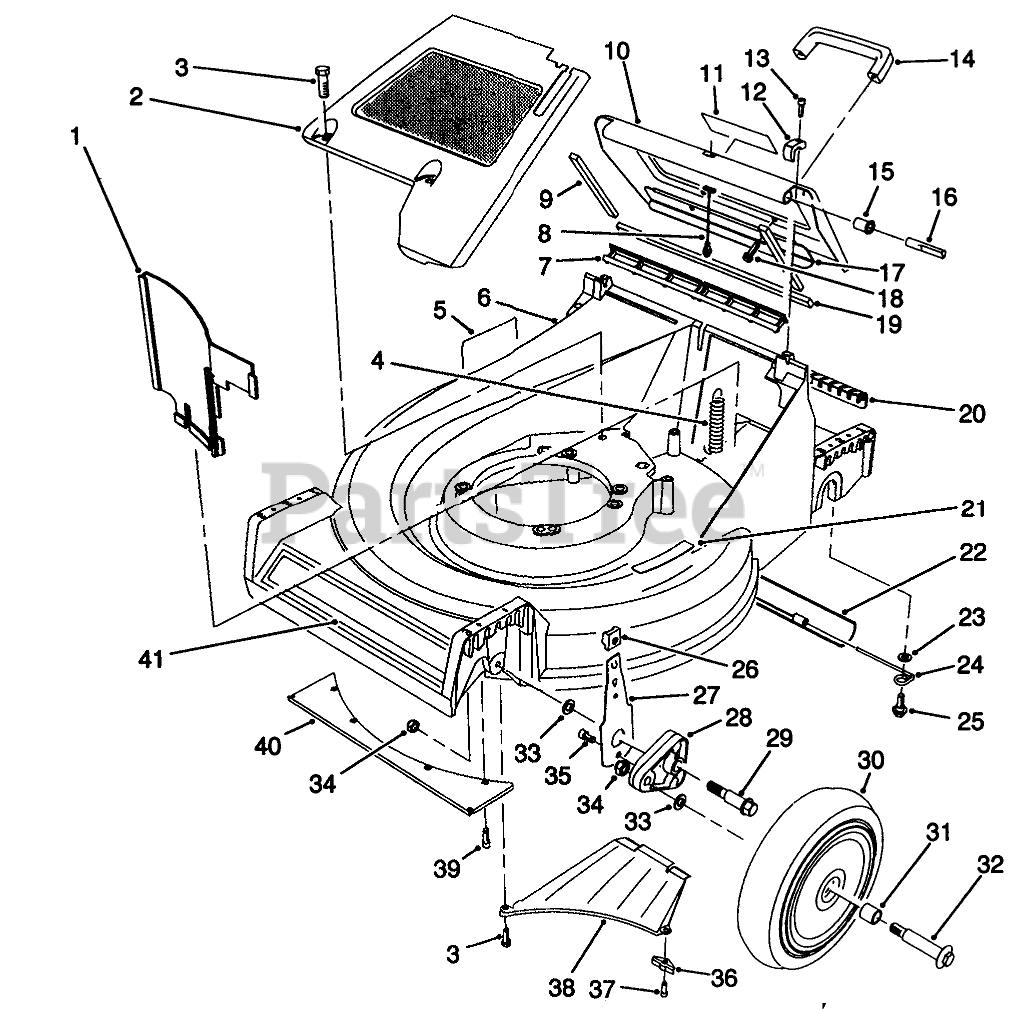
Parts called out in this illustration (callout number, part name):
1	PANEL-VERTICAL
2	PaneI-Screen
3	SCREW-HWHTF
4	EXTENSION-SPRING
5	Decal Danger
6	Housing-53cm (Model 26625B Only)(Incl. Ref. #5, 21 & 41)
7	DOOR SEAL
8	DOOR CABLE
9	DOOR SIDE SEAL
10	Door-Discharge (Incl. Ref. #9, 11 & 19)
11	DECAL - DANGER
12	HINGE CLAMP
13	SCREW-HSH
14	HANDLE-DOOR
15	DOOR BUSHING
16	HINGE PIN
17	DOOR - BRACE
18	SCREW-HWH
19	DOOR END SEAL
20	ACCESS COVER
21	DECAL - STEP PAD INT'L
22	TRAILING SHIELD
23	WASHER-PLAIN
24	SHIELD HANGER
25	SCREW-SHOULDER
26	KNOB-ARM
27	FRONT SPRING ARM ASM
28	ARM-PIVOT, FRONT
29	BOLT-SHOULDER
30	Wheel & Tire Assembly (Incl. Ref. #31)
31	BUSHING
32	WHEEL BOLT
33	WASHER
34	NUT-LOCK
35	SCREW-HSH, THREAD FORMING
36	Bracket-Discharge
37	SCREW-HWHTF
38	Ramp Discharge
39	SCREW-HWH
40	FRONT GUARD
41	DECAL - 53 CM
